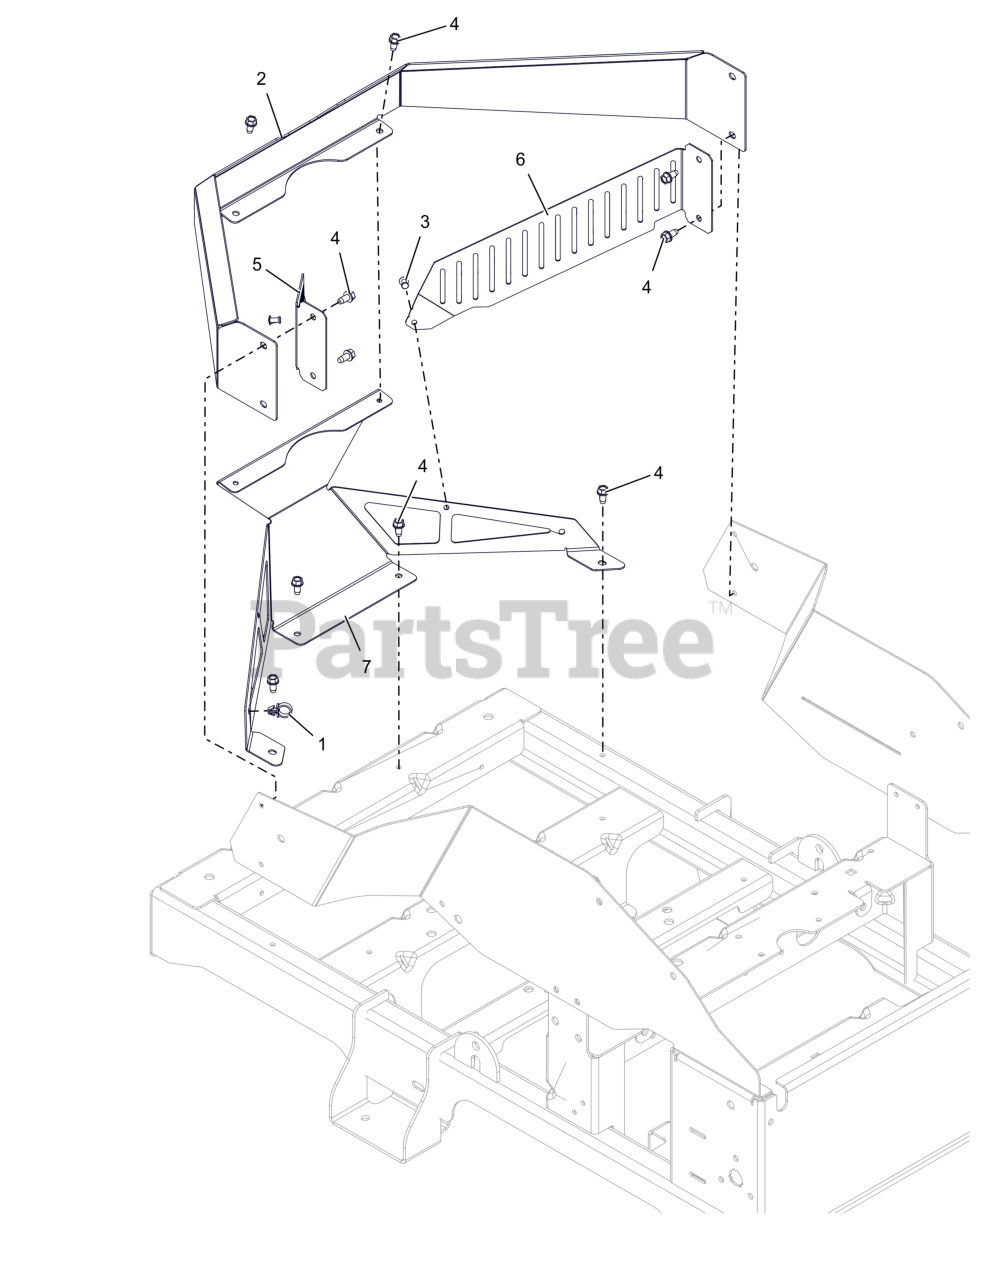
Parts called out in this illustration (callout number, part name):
1	ROUTING CLIP (1/2" ID)
2	WRAP, REAR (ORANGE)
3	RVT .187X.575 DOME AL BLACK
4	SCR-TAP .25-20X.50 HWH ZCC
5	SHIELD, LH ENGINE GUARD EDGE
6	SHIELD, MUFFLER EDGE CE
7	WRAP, REAR EDGE CE
